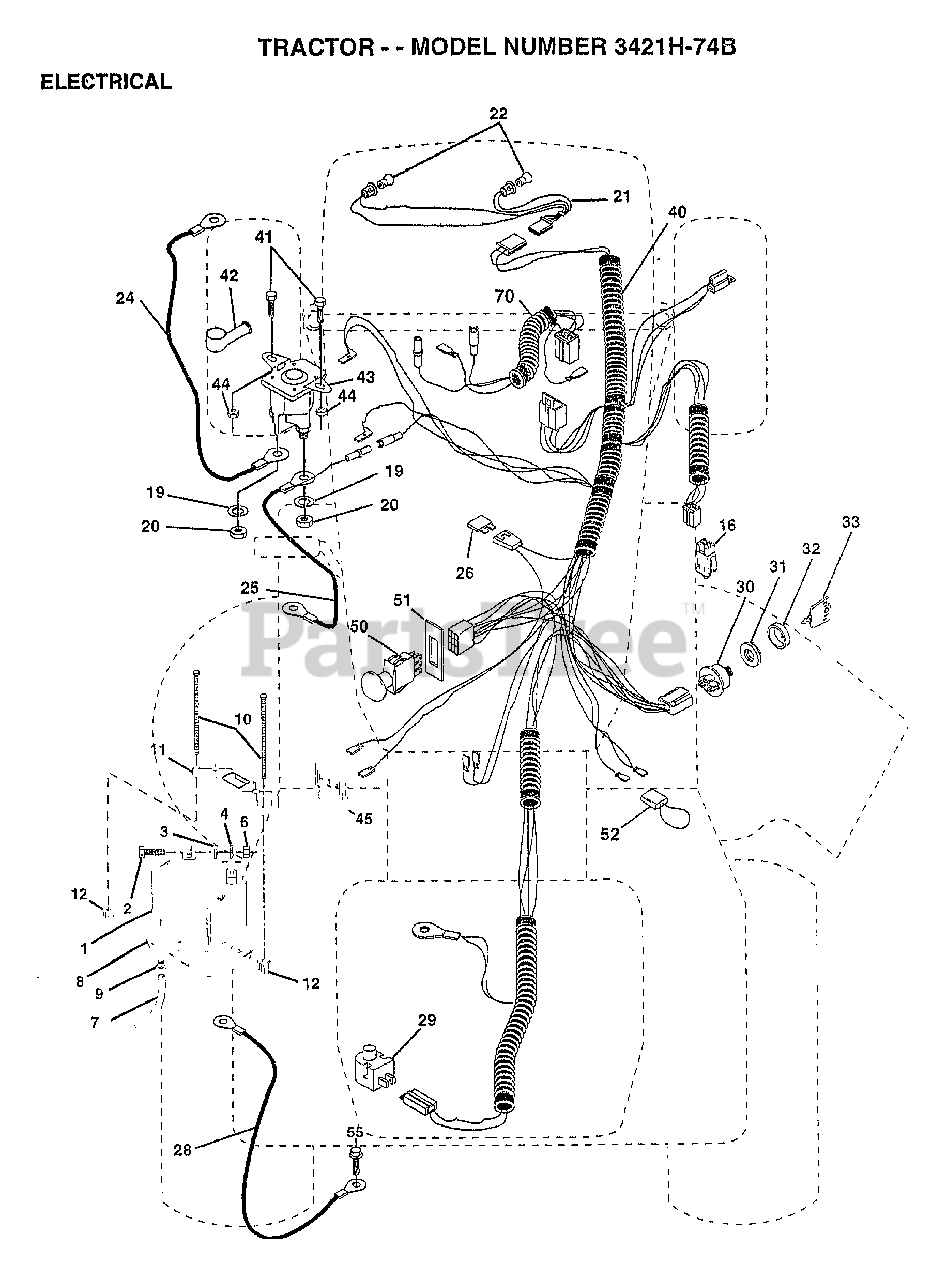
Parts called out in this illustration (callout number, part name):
2	BOLT LT
3	WASHER
4	LOCKWASHER
7	"DRAIN TU T, BATT"
8	"TRAY T, BATTERY"
9	HOSE CLAMP T
11	HOLDDOWN BATTERY
16	SWITCH INTERLOCK
20	NUT
21	"HARNESS,LIGHT SOC"
22	HEADLAMP BULB
24	CABLE.6GA.22W/16W
25	"CABLE T, BATTERY"
26	FUSE HYT
28	CABLE.GRND.6GA.21
29	SWITCH SEAT
30	SWITCH IGN 4POS
31	NUT IGNITION
32	COVER KEY SWITCH
33	KEY
40	HARNESS IGNITION
41	BOLT HXHD FIN
44	NUT HXKEP 1/4X20
45	AMMETER
50	PTO SWITCH.BLK
51	RING RETAIN PTO
52	PROTECTION LOOP
55	SCREW LT
70	HARNESS ENG B&S
